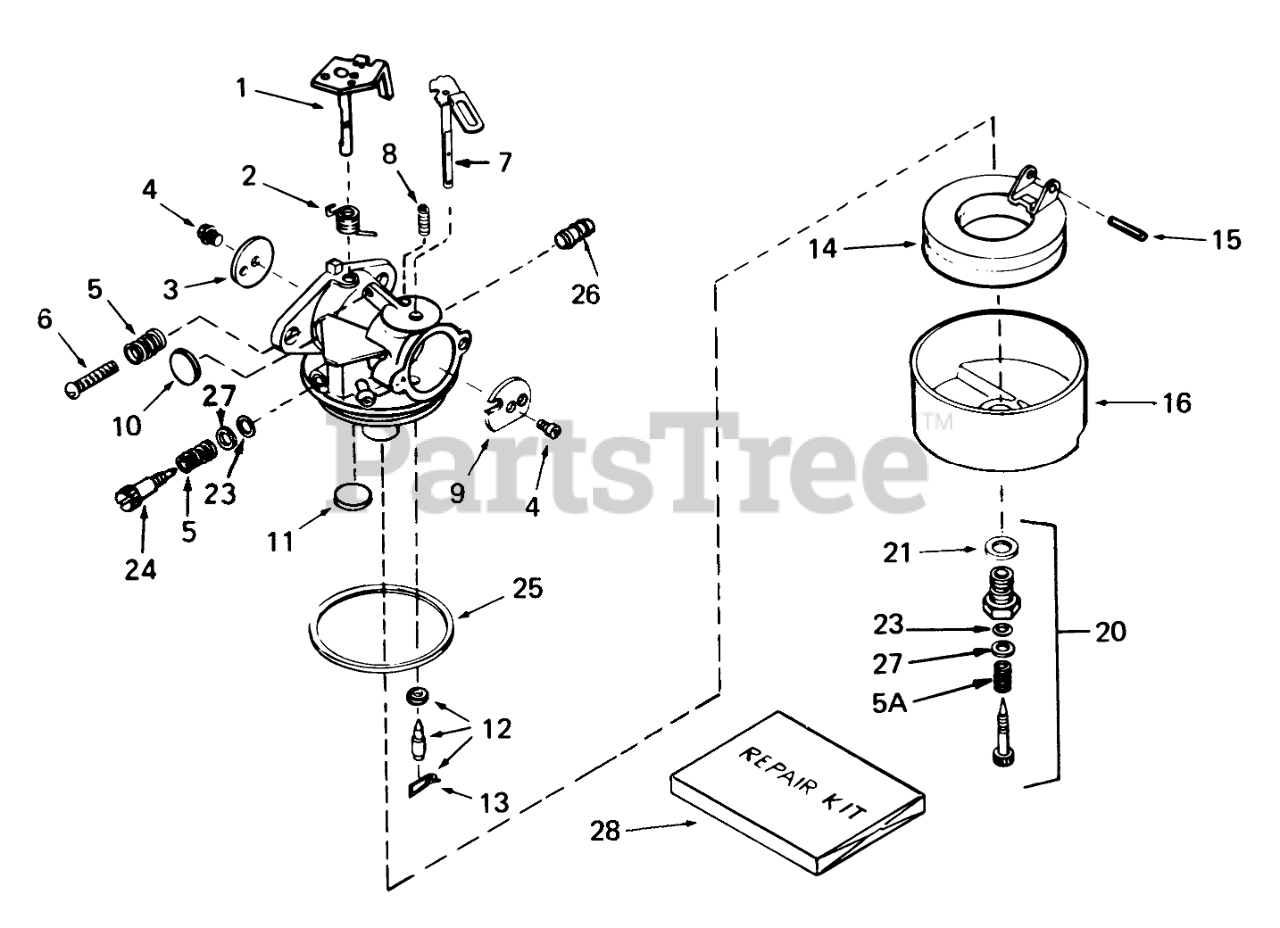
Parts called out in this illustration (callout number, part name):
1	Shaft/Lever-Throttle
2	Spring-Return, Throttle
3	Shutter-Throttle
4	Screw-Shutter
5	Spring-Tension
6	Screw-Throttle Crack Screw / Idle Speed
7	Choke Shaft and Lever ASM
8	Spring-Positioning, Choke
9	Shutter, Choke
10	Plug-Welch, Idle Mixture Well
11	Plug-Welch, Atmospheric Vent
12	Inlet Needle, Seat & Clip Assy. (Incl. Ref. #13)
13	Clip-Spring
14	Float
15	Shaft-Float
16	Bowl-Float (no drain)
20	Adjustment Screw Assy., Main (Incl. Ref. #5A, 21, 23 & 27)
21	Washer-Bowl Nut
23	"O"Ring
24	Screw Main Adjustment
25	O Ring-Bowl, Float
26	Fuel Fitting
28	Repair Kit
